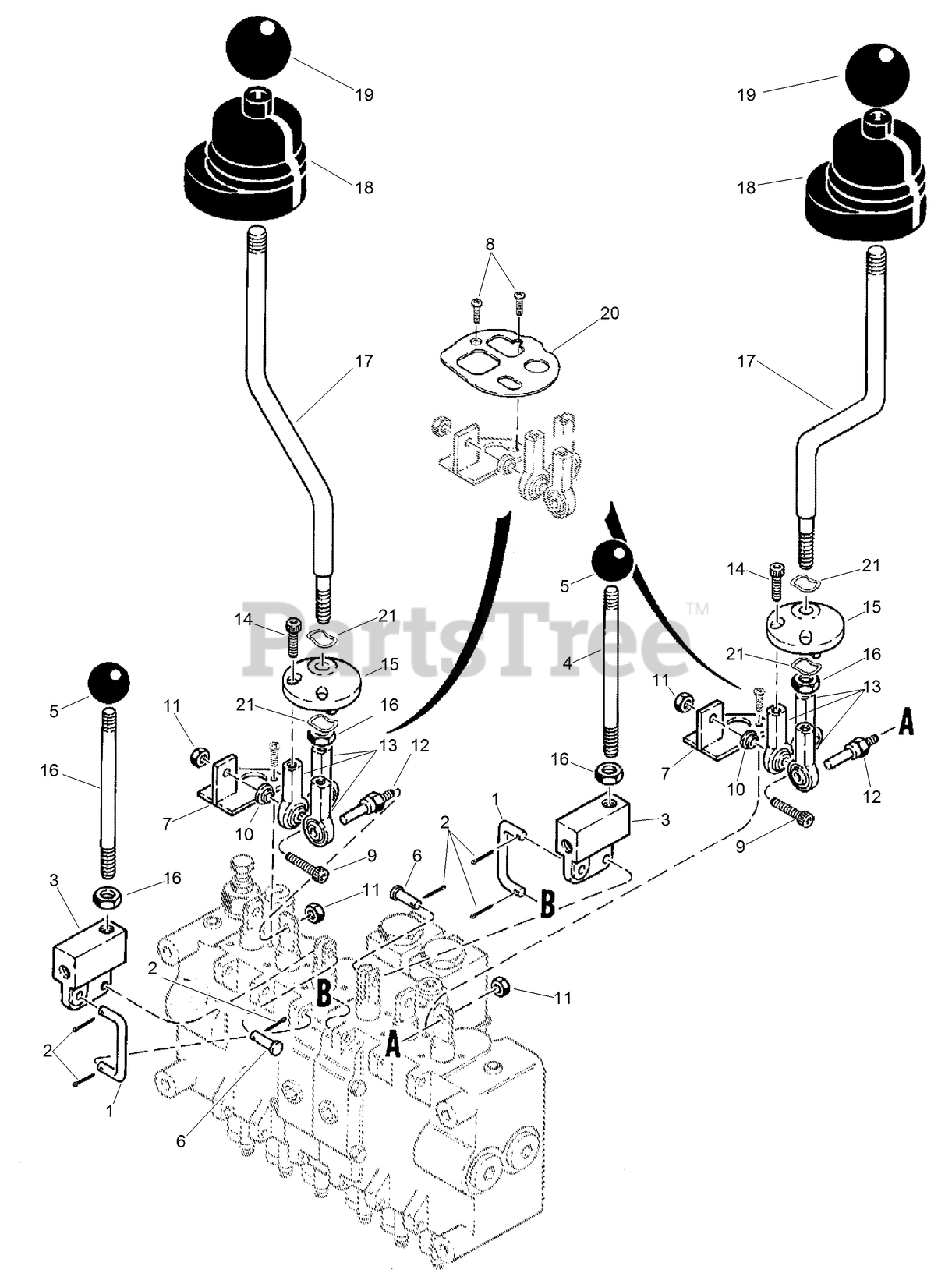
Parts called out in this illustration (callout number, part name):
2	PIN-COTTER
6	PIN-CLEVIS
7	BRACKET
11	NUT-JAM
13	END-ROD
15	ADAPTER
16	NUT-JAM
